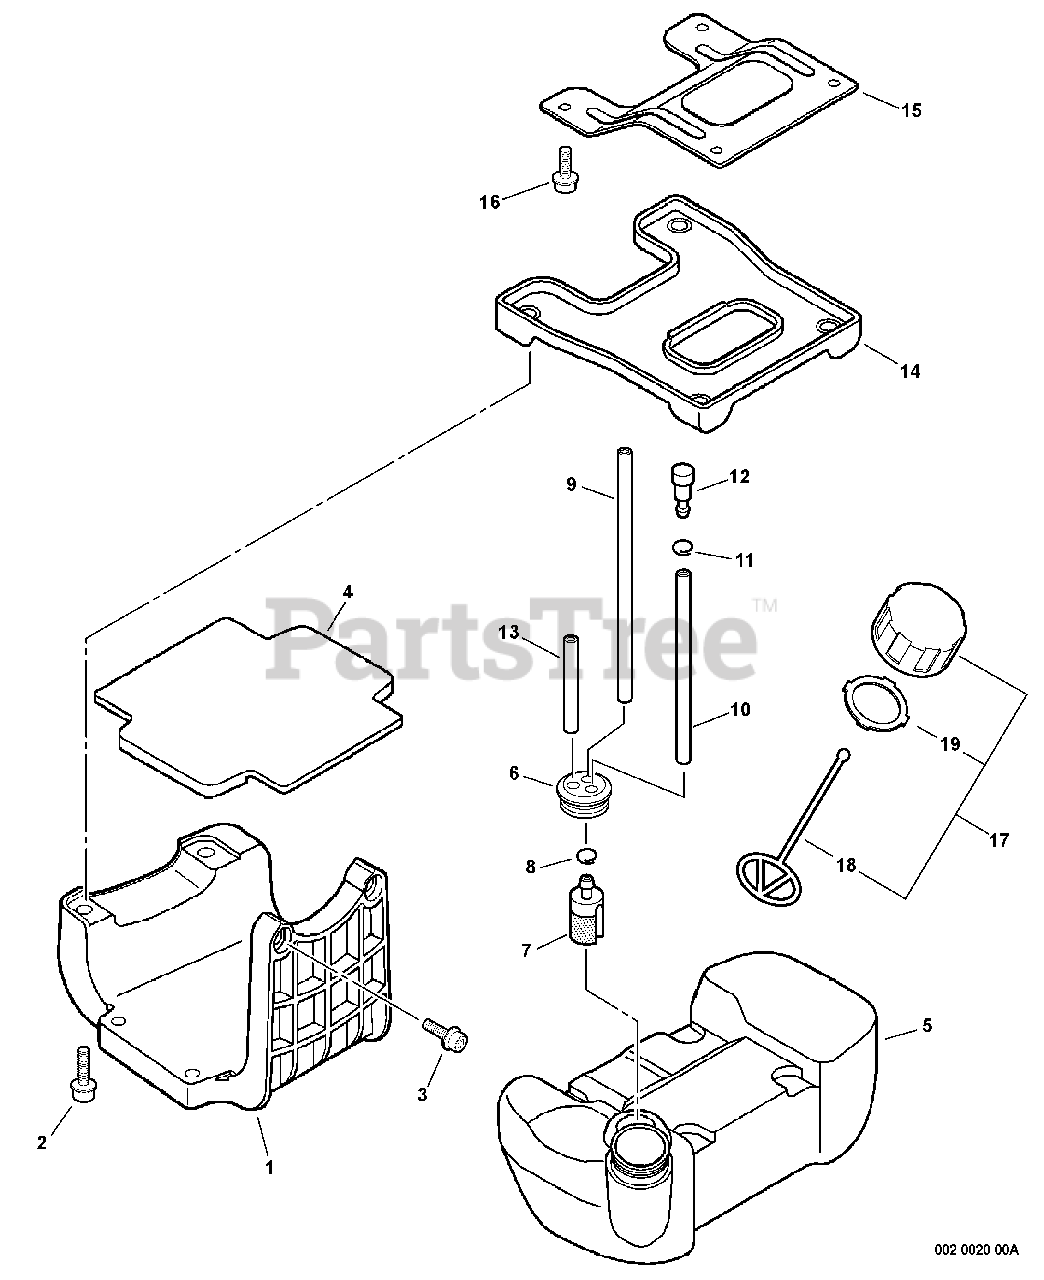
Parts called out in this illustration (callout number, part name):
1	BRACKET, FUEL TANK
2	SCREW - 5X20
3	SCREW - 5X25
4	CUSHION, TANK - LOWER
5	TANK, FUEL
6	GROMMET
7	FILTER, FUEL
8	CLIP - 6.5
9	PIPE - 3X6X180 -- BLACK
10	PIPE - 3X6X120 -- BLACK
11	CLIP - 6.5
12	VENT, FUEL TANK
13	PIPE - 3X6X60 -- CLEAR
14	CUSHION, TANK - UPPER
15	BRACKET, FUEL TANK
16	SCREW - 5X12
17	CAP ASSY - ORANGE
18	CONNECTOR, CAP
19	GASKET, CAP
